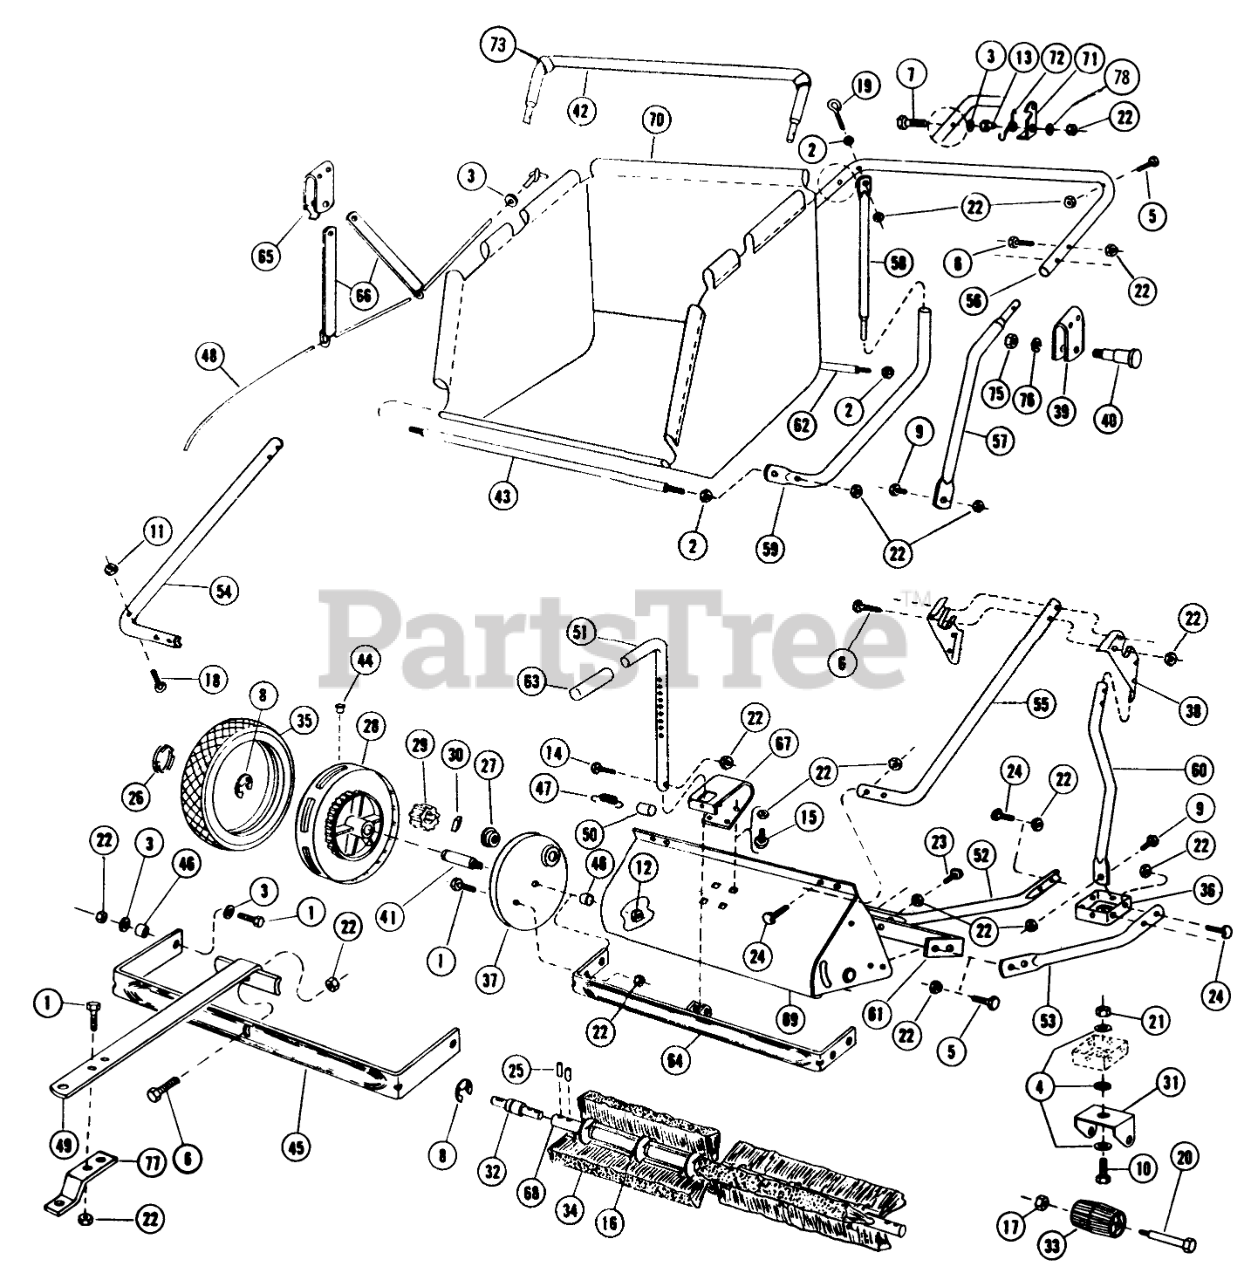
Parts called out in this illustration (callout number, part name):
1	Bolt
2	Nut
3	WASHER 5/16 SAE
4	Washer
5	Bolt
6	Bolt
7	Bolt
8	RING LAM L 262
9	H H C S
10	Bolt
11	Nut
12	NUT-6
13	Bolt Nut 5/16-18
14	HHCS
15	Bolt-Carriage 5/16-18 x 5/8
16	SPRING
17	NUT-6
18	Bolt-Eye 1/4-20 x 2
19	Bolt-Eye 5/16-18 x 2 3/4
20	STUD CASTER
21	Eslok Nut
22	Nut
23	Bolt-Tube 5/16-18 x 1 1/4
25	ROLLPIN 3/16 X 7/8
25	Bolt
26	PLUG BUTTON
27	BEARING
28	Wheel Ass-y.
29	PINION GEAR
30	PINION PAWL
31	Bracket-Caster
32	BRUSH STUB AXLE
32	AXLE BRUSH STUD
33	CASTER ROLLER
34	STRIP
34	STRIP BRUSH
35	Tire 10 x 2.25
36	Caster, Plate Ass-y.
37	SHIELD WHEEL
38	Bracket-Frame Pivot
39	Bracket-Hamper Pivot
40	PIVOT PIN
41	WHEEL STUD
42	Tube-Pivot Stand
43	Rod-Hamper Tie
44	Oiler
45	Hitch-U Bar
46	Spacer
47	Spring-Adjustment
48	Dump Rope
49	Tongue-Hitch
50	TUBE SPRING
51	TUBE ADJUSTING
52	Brace-Pivot Stand
53	Brace-Pivot Stand
54	Tube R.H. Support
55	Tube L.H. Support
56	GAUGE CAP
56	Tube Top Hamper
57	Tube Side Hamper
59	Tube Bottom
60	Support R.H. Pivot
60	Support L.H. Pivot
61	Stiffner-Bar
62	Rod-Rear Hamper
64	Bumper Ass-y.
65	ASSY BRACKET
66	Lever-Dump
67	Bracket-Adjustment
68	ASSY BRUSH AXLE & DS
68	Axle-Brush
69	Shield-Ass-y.
70	HAMPER ASSY
70	Hamper-Ass-y.
71	Latch-Hamper
72	Spring-Latch
73	Sleeve-Rubber
75	NUT-6
76	LOCKWASHER
77	BRACKET-HITCH PIN
78	Washer, 7/16
